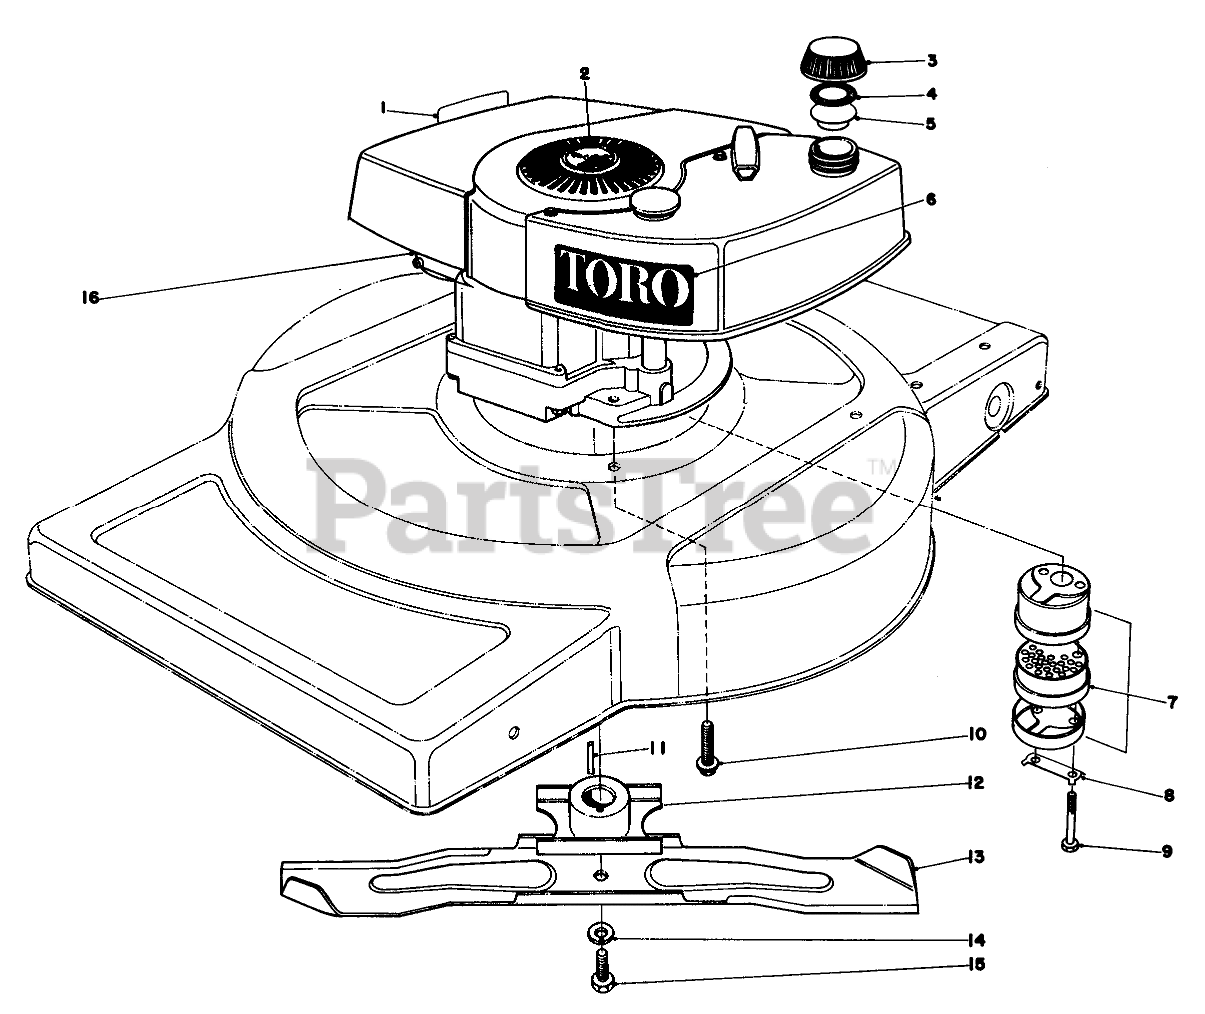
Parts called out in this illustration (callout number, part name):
1	Decal-Maintenan
2	PLUG BUTTON
3	Gas Cap (Incl. Ref. #4 & 5)
4	GASKET
5	GAS CAP BAFFLE
6	Decal
7	Muffler Assy. (Incl. Ref. #8 & 9)
8	CLIP - LOCKING
9	SCREW-HH
10	SCREW-HWHTF
11	Square Key
12	BLADE RETAINER WA(BLACK)
13	Blade
14	WASHER-LOCK
15	BLADE SCREW
16	Engine
